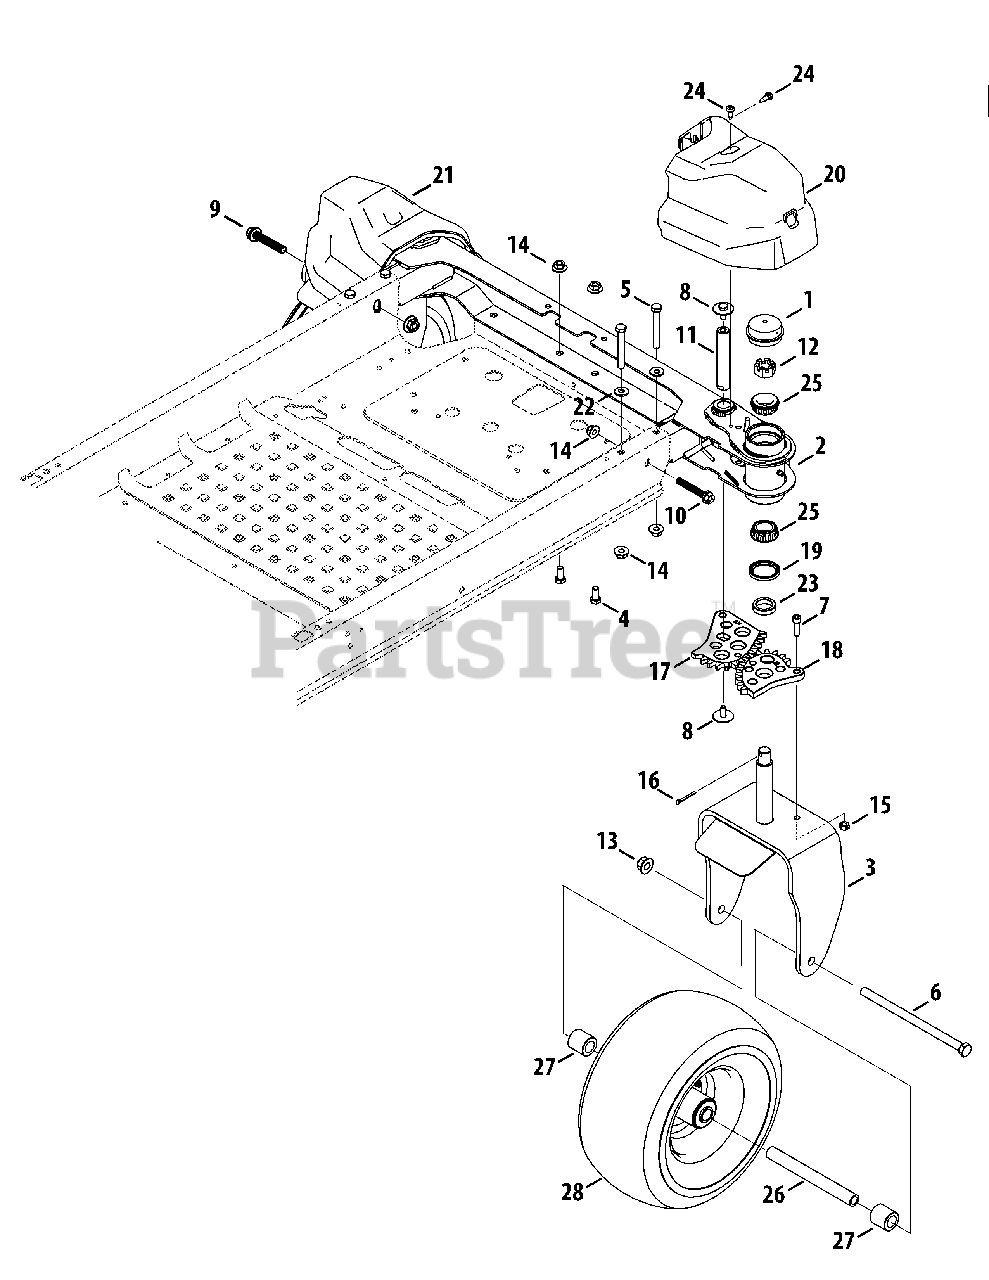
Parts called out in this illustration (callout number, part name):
1	Cap
2	Front Axle
3	Caster Wheel Bracket
4	Hex Cap Screw, 3/8-16 x .75
5	Screw, 3/8-16 x 2.75
6	Hex Cap Screw, 1/2-13 x 8.50
7	Socket Head Screw, 5/16-18 x 1.00
8	Hex Cap Screw, 5/16-18 x .75
9	Hex Flange Screw, 3/8-16 x 2.25
10	Hex Flange Screw, 3/8-16 x 2.00
11	Pivot Gear Steering Shaft
12	Slotted Nut, 3/4-16
13	Flange Lock Nut, 1/2-13
14	Flange Lock Nut, 3/8-16
15	Hex Lock Nut, 5/16-18
16	Cotter Pin, 5.32 x 1.25
17	12-Tooth Variable Gear
18	13-Tooth Variable Spur Gear
19	Seal, 35 x 47 x 5
20	Axle Cover, RH
21	Axle Cover, LH
22	Flat Washer, .385 x .870 x .092
23	Seal, 1.378 x .984 x .329
24	TORX SHOULDER SCREW 1/4-20
25	Bearing, 47mm x 25mm x 15mm
26	Spacer, .51 ID x .75 OD x 7.10
27	Hub, .76 x 1.23 x 1.25
28	Wheel Assembly, 13 x 6.5 x 6
